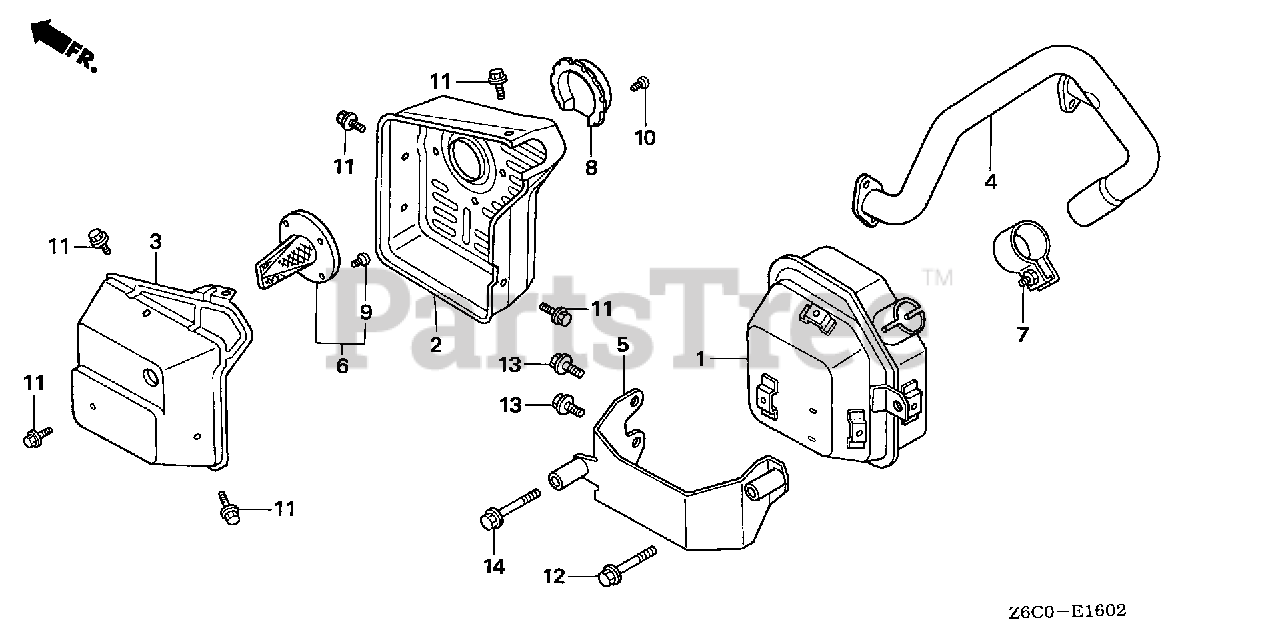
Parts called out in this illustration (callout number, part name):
1	MUFFLER COMP. (SIDE-L) (FUTABA) (SILVER MUFFLER)
2	PROTECTOR, MUFFLER (SIDE-L)
3	PROTECTOR, RR. MUFFLER (SIDE-L)
4	PIPE, EX. (SIDE-L)
5	STAY, MUFFLER (SIDE-L)
6	ARRESTER, SPARK
7	BAND ASSY. (NOT AVAILABLE)
9	SCREW (NELSON)
11	BOLT, FLANGE (6X8)
12	BOLT, FLANGE (6X50)
13	BOLT, FLANGE (8X14)
14	BOLT, FLANGE (8X50)
